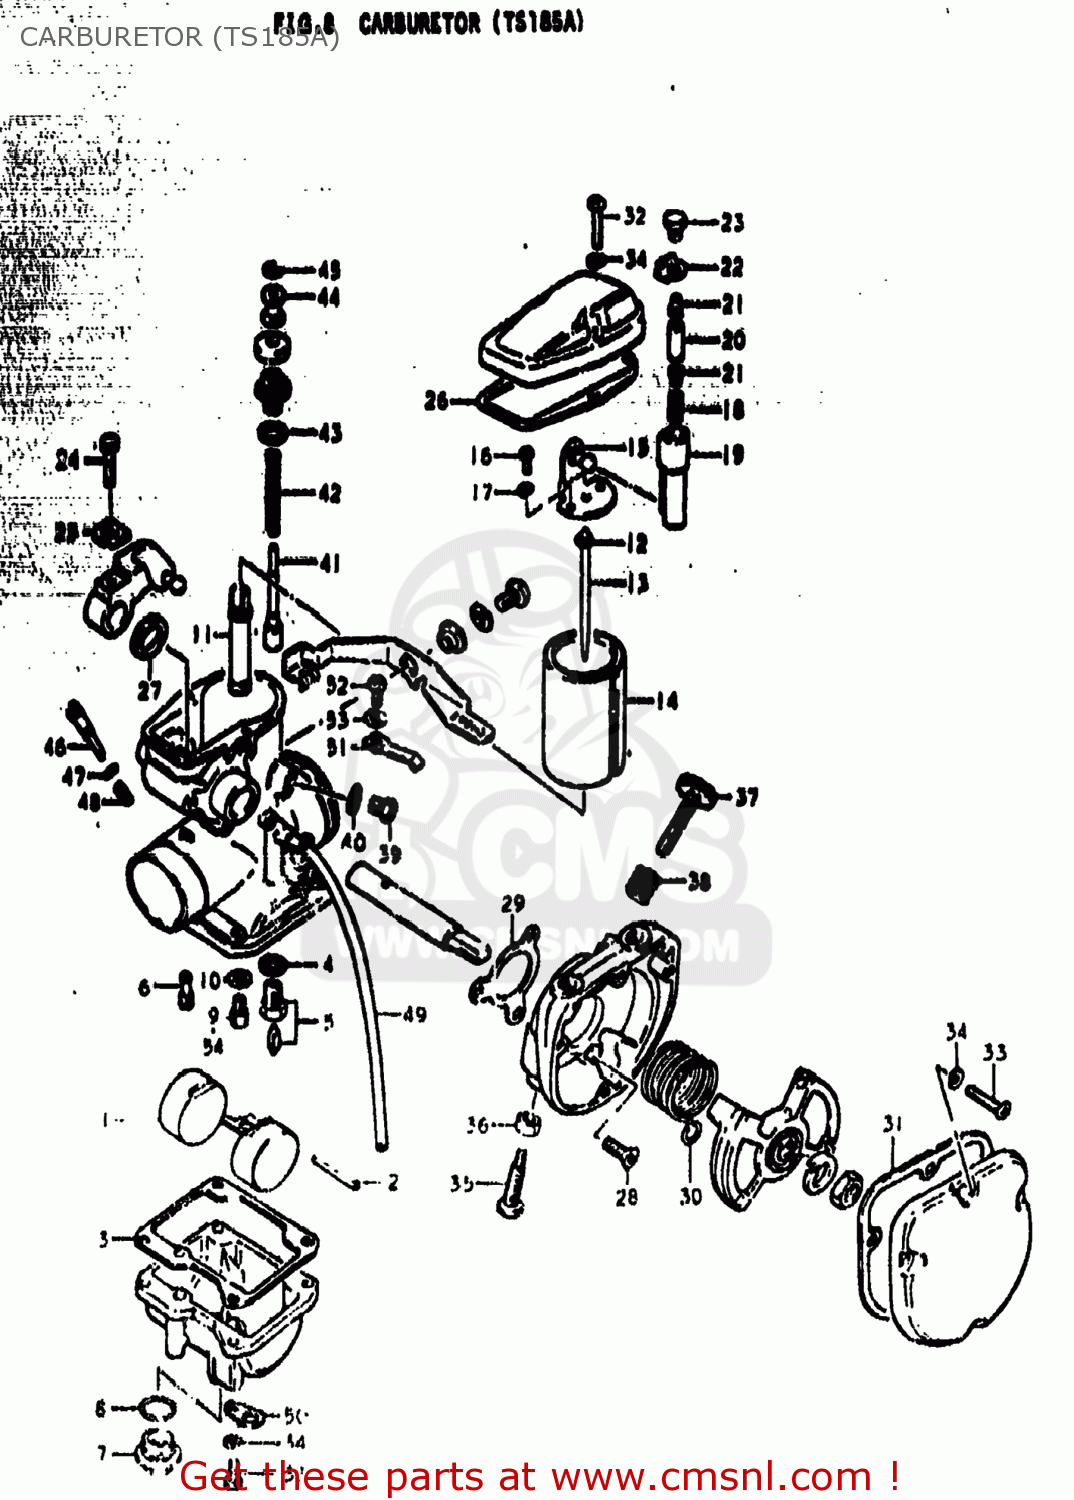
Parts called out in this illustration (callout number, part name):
1	FLOAT
2	PIN,FLOAT
3	GASKET,FLOAT CHAMBER (NAS)
4	GASKET,FLOAT CHAMBER (NAS)
5	VALVE ASSEMBLY,NEEDLE
6	JET
7	PLUG,DRAIN
8	O RING
9	JET,MAIN(130)
10	WASHER
11	JET,NEEDLE
12	CLIP
14	VALVE,THROTTLE
15	BRACKET,CARBURETOR
16	SCREW
17	LOCK WASHER
18	SPRING
19	LEVER ASSEMBLY
20	SPRING
21	PIN,CARBURETOR
22	PLATE,CARBURETOR
23	SCREW
24	BOLT
25	RING
26	GASKET,MIXING CHAMBER (NAS)
27	RING
28	SCREW(5X14)
29	GASKET,CARBURETOR CASE
30	SPRING
31	GASKET,CARBURETOR COVER
32	SCREW
33	SCREW
34	LOCK WASHER
35	SCREW
36	NUT
37	SCREW,THROTTLE STOP
38	SPRING,THROTTLE SCREW
39	BOLT
40	GASKET,THRO VALVE INSPECTION (NAS)
41	VALVE,STARTER
42	SPRING
43	O-RING
44	RING
45	CLIP,CARBURETOR STARTER
46	SCREW,PILOT AIR ADJUSTING
47	O RING
48	SPRING
49	HOSE
50	PLATE
51	SPRING
52	SCREW
53	LOCK WASHER
54	JET
